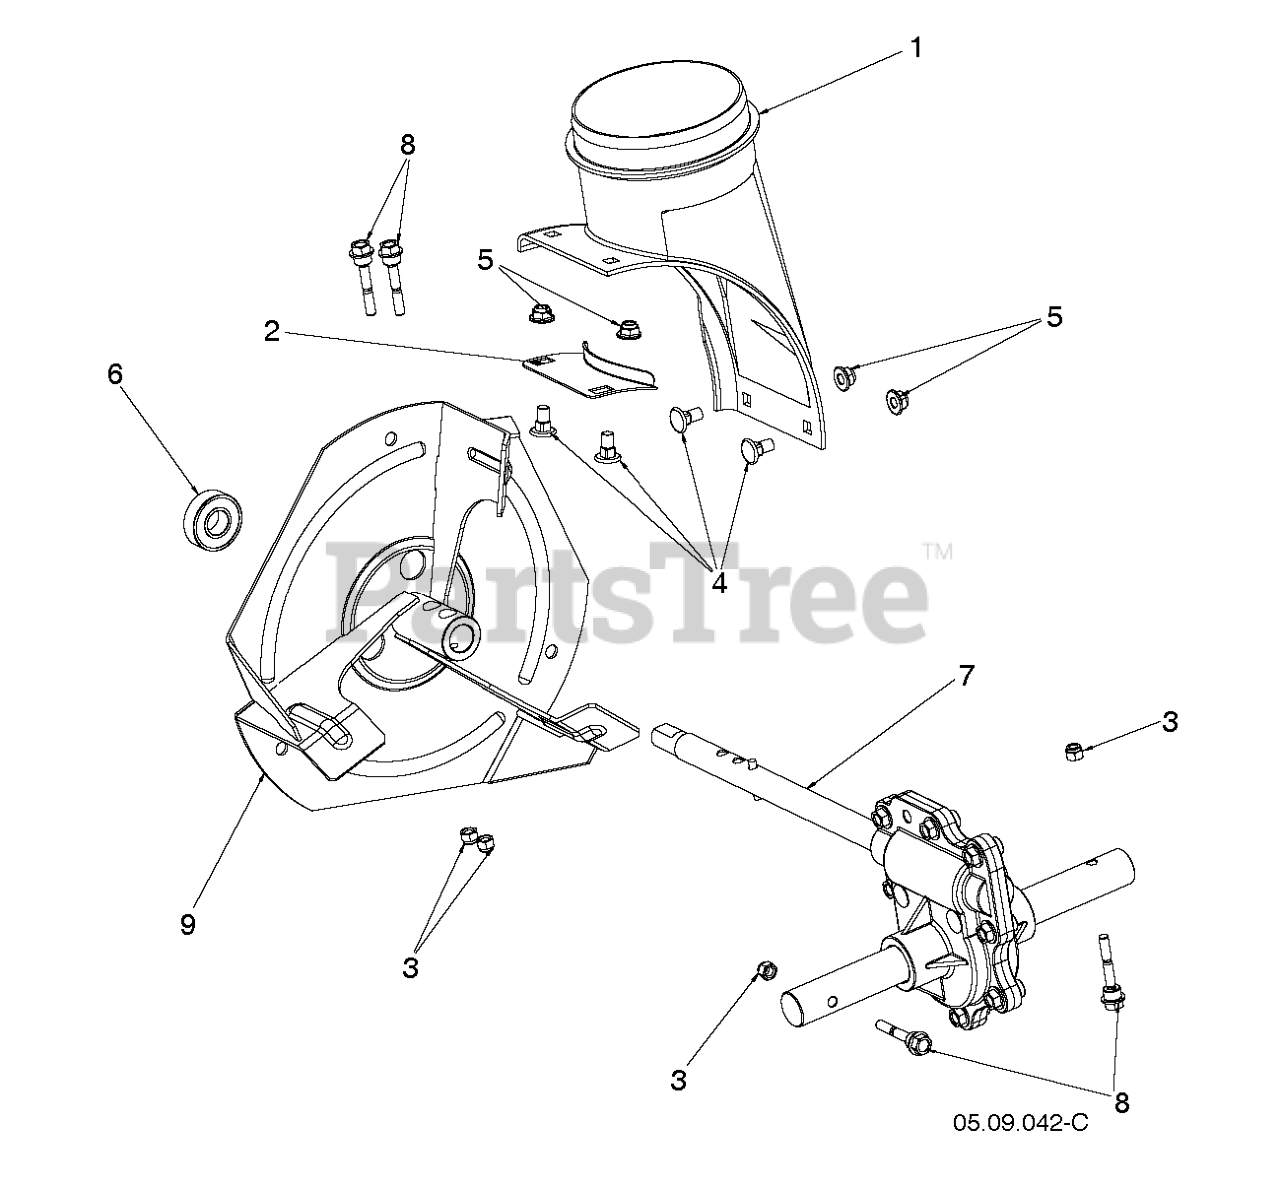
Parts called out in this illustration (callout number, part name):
1	CHUTE.DISCHARGE.BASE
3	NUT HEXAGON 1/4-20 ST ZPB
4	BOLT CARR WAFER BLK 5_16-18 X
5	NUT HEX FLG NYLOCK BLK 5_16-1
8	BOLT SHEAR HX HD 1/4-20 CLEAR
9	IMPELLER.STEEL.SNOW.BLACK
